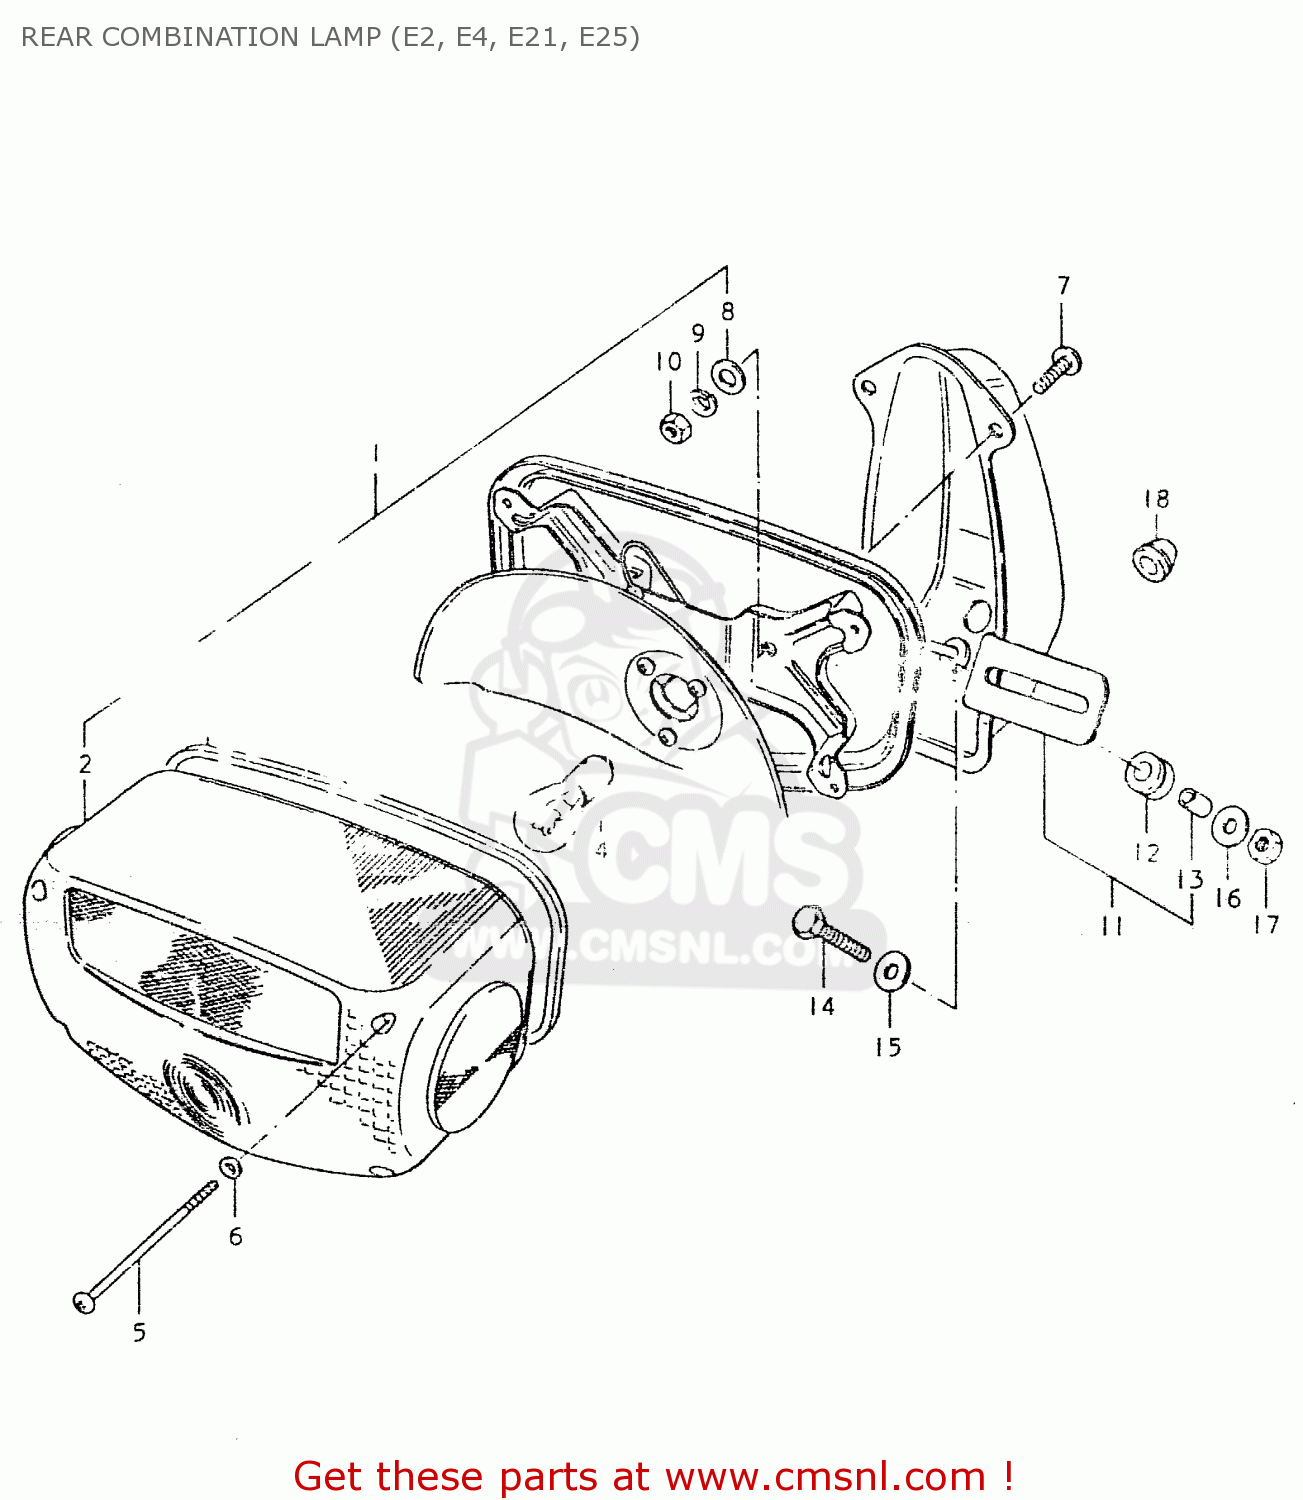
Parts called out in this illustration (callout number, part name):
1	LAMP UNIT, TAIL
2	LENS,REAR COMBINATION LAMP
3	GASKET (NAS)
4	BULB 12V21/5W
5	SCREW (4X55)
6	GASKET (NAS)
7	SCREW 6X12
8	WASHER
9	LOCK WASHER
10	NUT
11	BRACKET ASSY
12	CUSHION
13	SPACER,REAR COMBINATION LAMP
14	BOLT
15	WASHER (6.5X20X1.2)
16	WASHER
17	NUT
18	GROMMET
